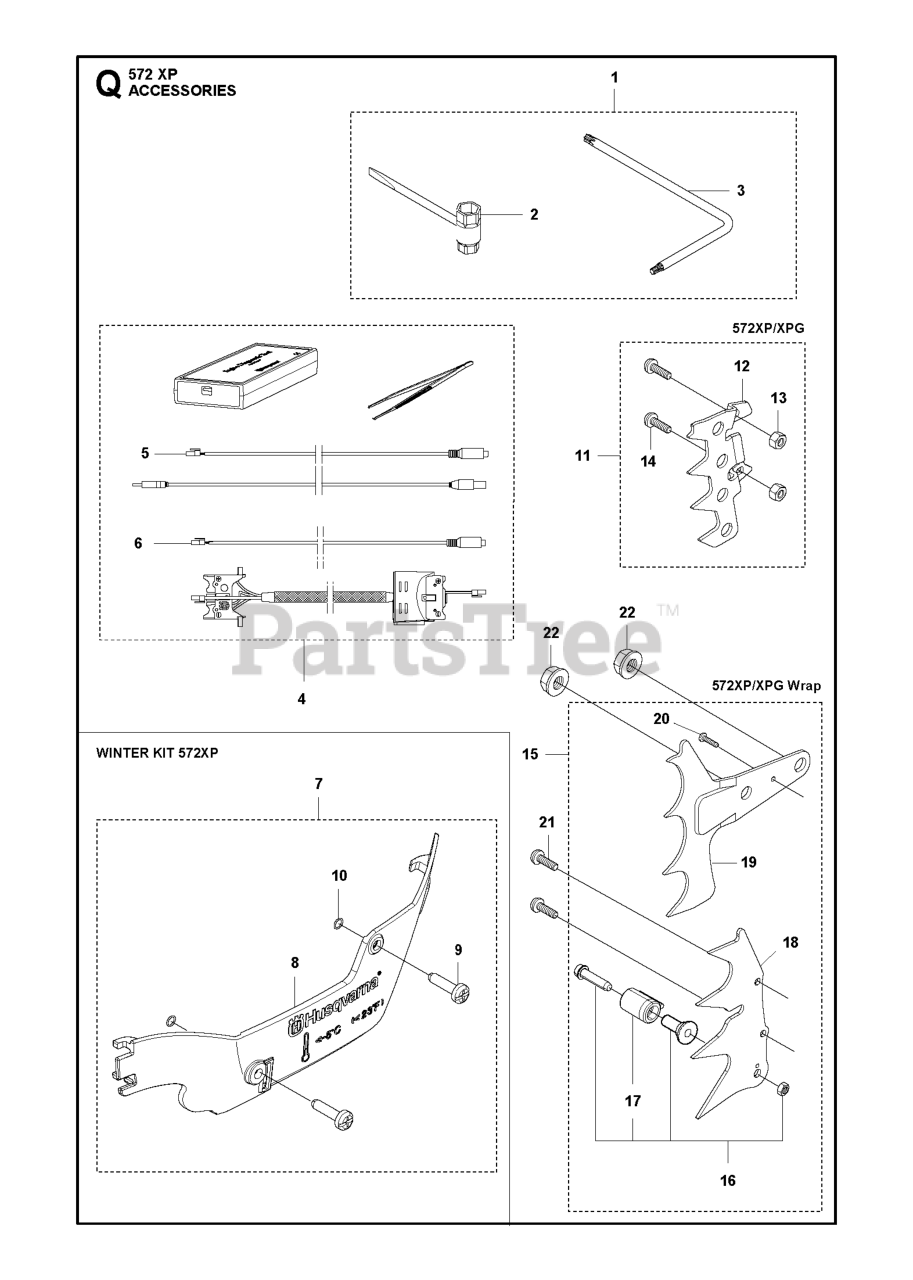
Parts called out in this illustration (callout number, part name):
2	COMBI TOOL
4	DIAGNOSTIC TOOL KIT
5	CABLE ASSY
6	CABLE ASSY
7	WINTER KIT
8	WINTER COVER
11	SPIKE KIT - OUTER STD H565/H57
12	SPIKE OUTER H565/H572
14	SCREW ITXSCFM
15	SPIKE KIT WESTCOAST H565/H572
16	CHAIN CATCHER H565/H572 KIT
18	FELLING DOG
19	FELLING DOG
20	SCREW CITXPANT
21	SCREW ITXSCM
22	NUT M8 FLANGE
